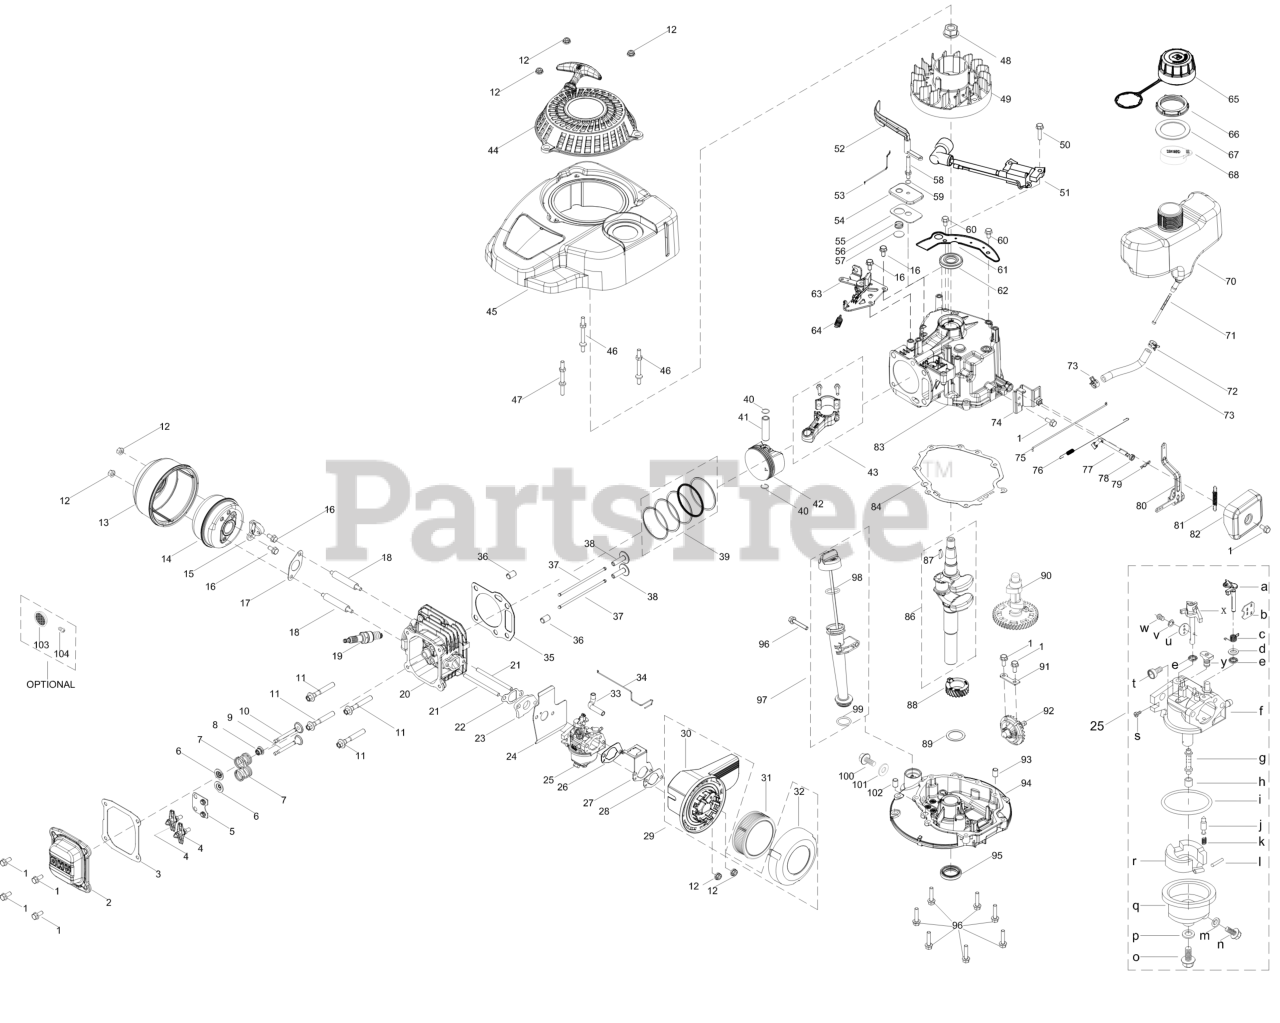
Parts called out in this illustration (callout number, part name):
1	BOLT M6-1 x 14 GR8.8
2	VALVE COVER
3	VALVE COVER GASKET
4	ROCKER ARM ASSEMBLY
5	PUSH ROD GUIDE
6	VALVE SPRING RETAINER
7	VALVE SPRING
8	INTAKE VALVE SEAL
9	EXHAUST VALVE
10	INTAKE VALVE
11	SCREW M8 x 54 GR10
13	MUFFLER SHIELD
14	MUFFLER ASSEMBLY
15	THERMOSTAT CONTROL CHOKE
16	BOLT M6-1 x 12 GR8.8
17	MUFFLER GASKET
18	STUD M6-1 x 76
19	SPARK PLUG
20	CYLINDER HEAD
21	CARBURETOR STUD-M6 x 87
22	CARBURETOR INSULATOR GASKET
23	CARBURETOR INSULATOR
24	CARBURETOR GASKET
25	CARBURETOR
26	AIR FILTER BASE GASKET
27	CHOKE TEMP CONTROL BRACKET
28	AIR FILTER BRACKET GASKET
29	AIR FILTER ASSEMBLY
30	AIR FILTER BASE
31	PAPER AIR FILTER
32	AIR FILTER COVER
33	BREATHER HOSE
34	CHOKE TEMP CONTROL LINKAGE
35	CYLINDER HEAD GASKET
37	PUSH ROD
38	TAPPET (LIFTER)
39	PISTON RING SET
40	SNAP RING-PISTON PIN
41	PISTON PIN
42	PISTON
43	CONNECTING ROD ASSEMBLY
44	STARTER RECOIL ASSEMBLY
45	ENGINE SHROUD ASSEMBLY
46	STUD M6 x 75
47	STUD M6 x 73
48	FLYWHEEL NUT
49	FLYWHEEL
50	BOLT M6-1 x 25 GR8.8
51	IGNITION COIL ASSEMBLY
53	ENGINE CHOKE
54	BREATHER COVER PLATE
55	BREATHER COVER GASKET
56	BREATHER VALVE SPRING
57	BREATHER VALVE
58	PIVOT VANE STUD
59	FLAT WASHER 6x1x18
60	BOLT M6-1 x 10 GR8.8
61	SHROUD COVER PLATE
62	UPPER CRANKSHAFT SEAL
63	ENGINE BRAKE ASSEMBLY
64	BRAKE SPRING
65	FUEL CAP W/TETHER
66	FUEL TANK NUT
67	FUEL TANK UPPER GROMMET
68	FUEL TANK DUST CAP
70	FUEL TANK
71	FUEL FILTER
72	HOSE CLAMP
73	FUEL HOSE
74	COMPONENT BRACKET
75	THROTTLE LINKAGE
76	THROTTLE LINKAGE SPRING
77	GOVERNOR ARM SHAFT
78	GOVERNOR SEAL
79	COTTER PIN
80	GOVERNOR ARM ASSEMBLY
81	GOVERNOR SPRING
82	GOVERNOR SHIELD
83	CRANKCASE
84	CRANKCASE COVER GASKET
86	CRANKSHAFT
87	FLYWHEEL KEY
88	CRANKSHAFT TIMING GEAR
89	THRUST WASHER
90	CAMSHAFT
91	GOVERNOR GEAR MOUNTING PLATE
92	GOVERNOR GEAR/SHAFT ASSEMBLY
93	DOWEL PIN
94	CRANKCASE COVER
95	LOWER CRANKSHAFT SEAL
96	BOLT-M6-1 x 28 GR8.8
98	O-RING
100	OIL DRAIN PLUG
101	WASHER
102	DOWEL PIN
103	SPARK ARRESTOR
104	SCREW M3.5 x 9.5
